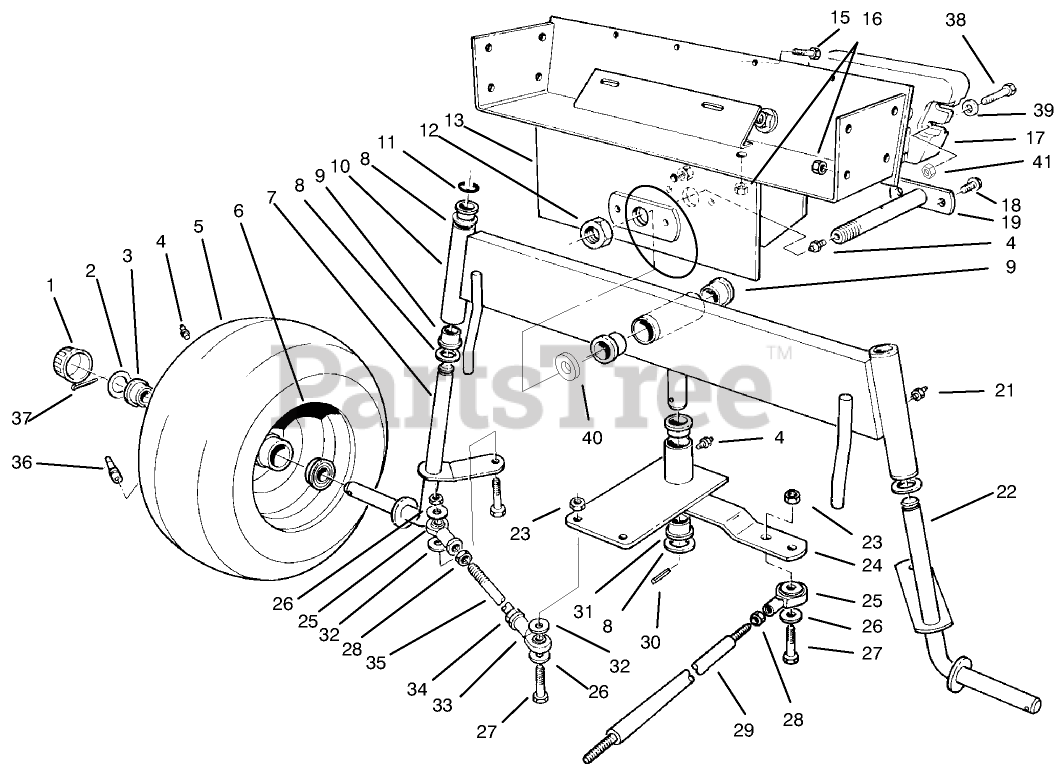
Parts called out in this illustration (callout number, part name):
1	CAP-HUB
2	WASHER-PLAIN
3	Bearing
4	FITTING-GREASE
6	FRONT WHEEL
7	Spindle R.H.
8	WASHER-THRUST
9	BUSHING PM
10	Axle-Rear (Incl. Ref. #9 & 20)
11	E-RING
12	NUT-LOCK NI
13	Frame-Rear
15	SCREW-HH
16	NUT-LOCK, NI
17	WEIGHT-REAR
18	SCREW-HHFTF
19	Axle-Pivot
21	GREASE FITTING
22	Spindle LH.
23	NUT-LOCK, NI
24	Plate-Pivot (Incl. Ref. #4 & 30)
25	BALL JOINT RH
26	WASHER-FLAT
27	SCREW-HH
28	NUT-JAM
29	Rod-Steering
30	PIN-ROLL
31	BEARING-FLANGE
32	WASHER
33	BALL JOINT LH
35	TIE ROD - STEERING
36	STEM-VALVE
37	PIN-COTTER
38	SCREW-HH
39	WASHER-LOCK
40	WASHER-FLAT
41	NUT-LOCK, NI
